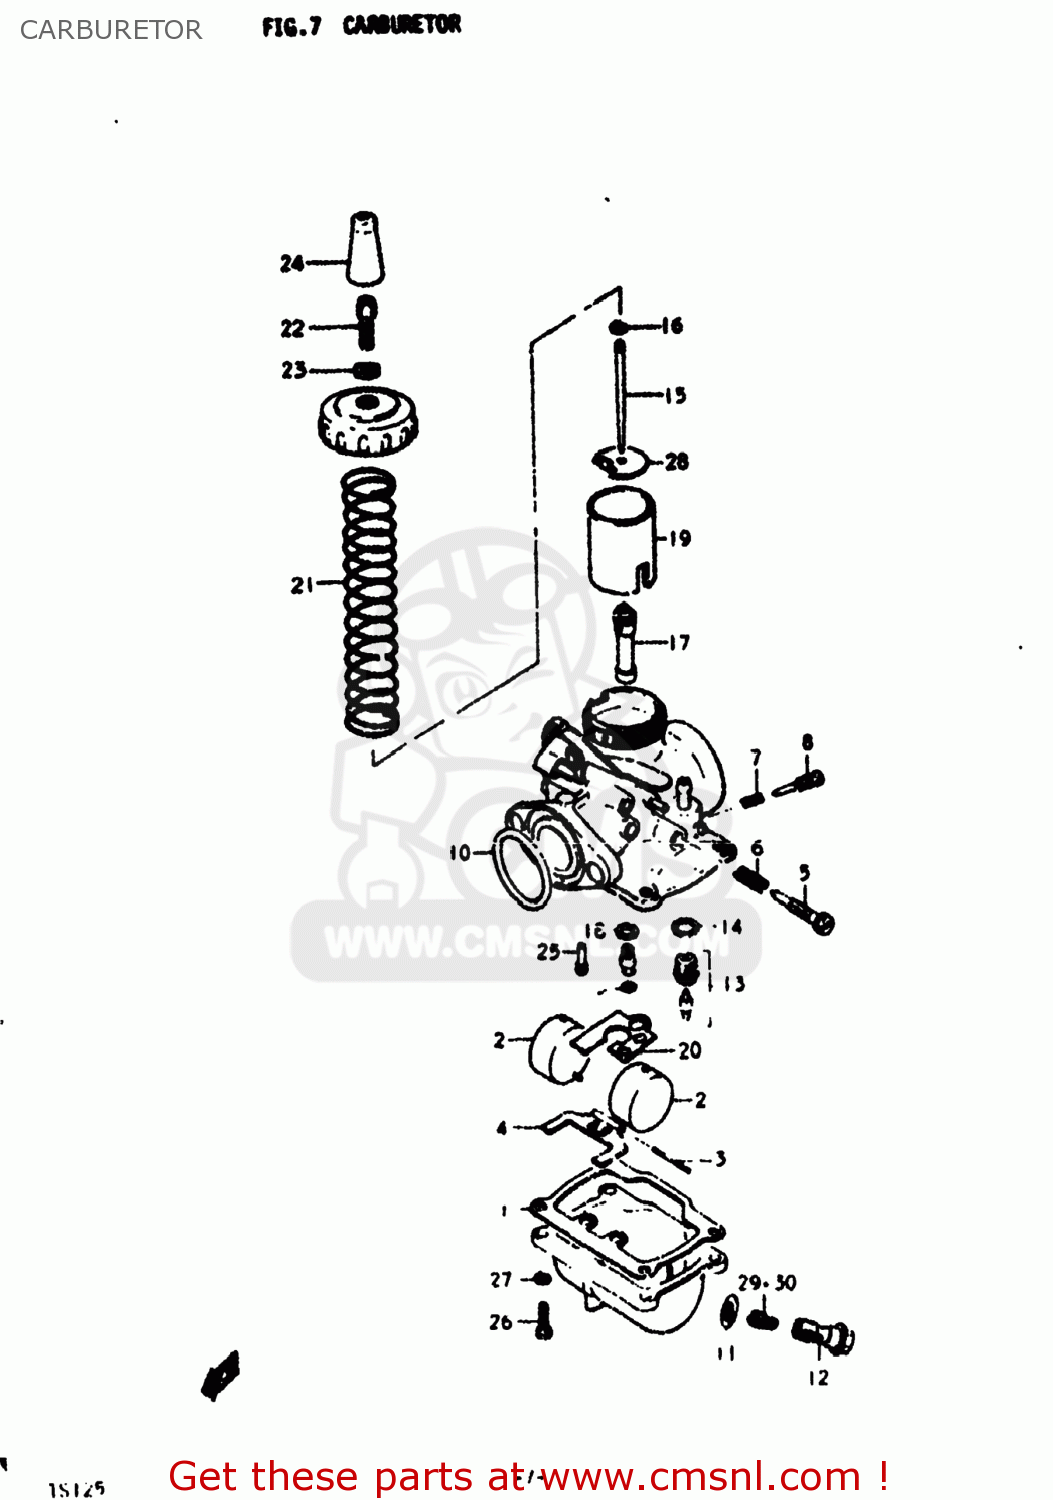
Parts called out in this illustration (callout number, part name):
0	CARBURETOR ASSEMBLY
1	GASKET,FLOAT CHAMBER (NAS)
2	FLOAT
3	PIN,FLOAT
4	ARM,FLOAT
5	SCREW,THROTTLE STOP
6	SPRING,THROTTLE SCREW
7	SPRING
8	SCREW,PILOT AIR
9	O RING
10	O RING
11	WASHER
12	HOLDER
13	VALVE ASSY,NEEDLE
14	GASKET,VALVE SEAT (NAS)
15	NEEDLE,JET
16	CLIP
17	JET,NEEDLE
18	WASHER
19	VALVE,THROTTLE
20	PLATE
21	SPRING, THROTTLE VALVE
22	ADJUSTER,CABLE
23	NUT
24	CAP
25	JET
26	SCREW
27	LOCK WASHER
28	SEAT,THROTTLE VALVE SPRING
29	JET
30	JET
